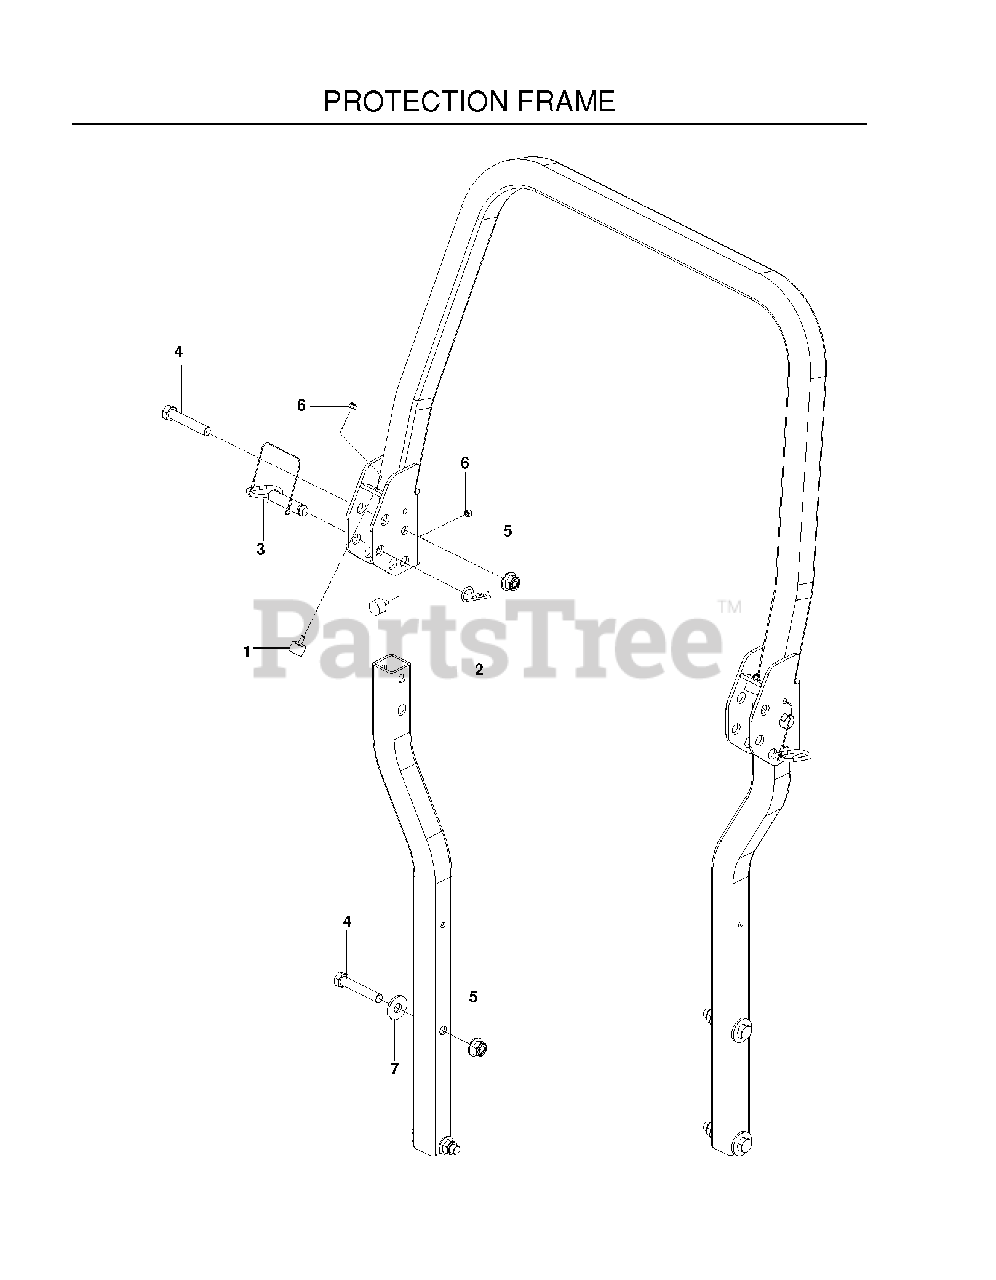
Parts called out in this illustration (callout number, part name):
1	BUMPER, MALE STUD, 1/4-20
2	PIN HAIR .148 X 2-15/16 #210
3	PIN, ROPS
4	5/8-11 X 3-1/2 HHB
5	NUT 5/8-11 FLG NYLOC ZD
6	NUT 1/4-20 NYLOC
7	WASHER, 5/8 FLAT
